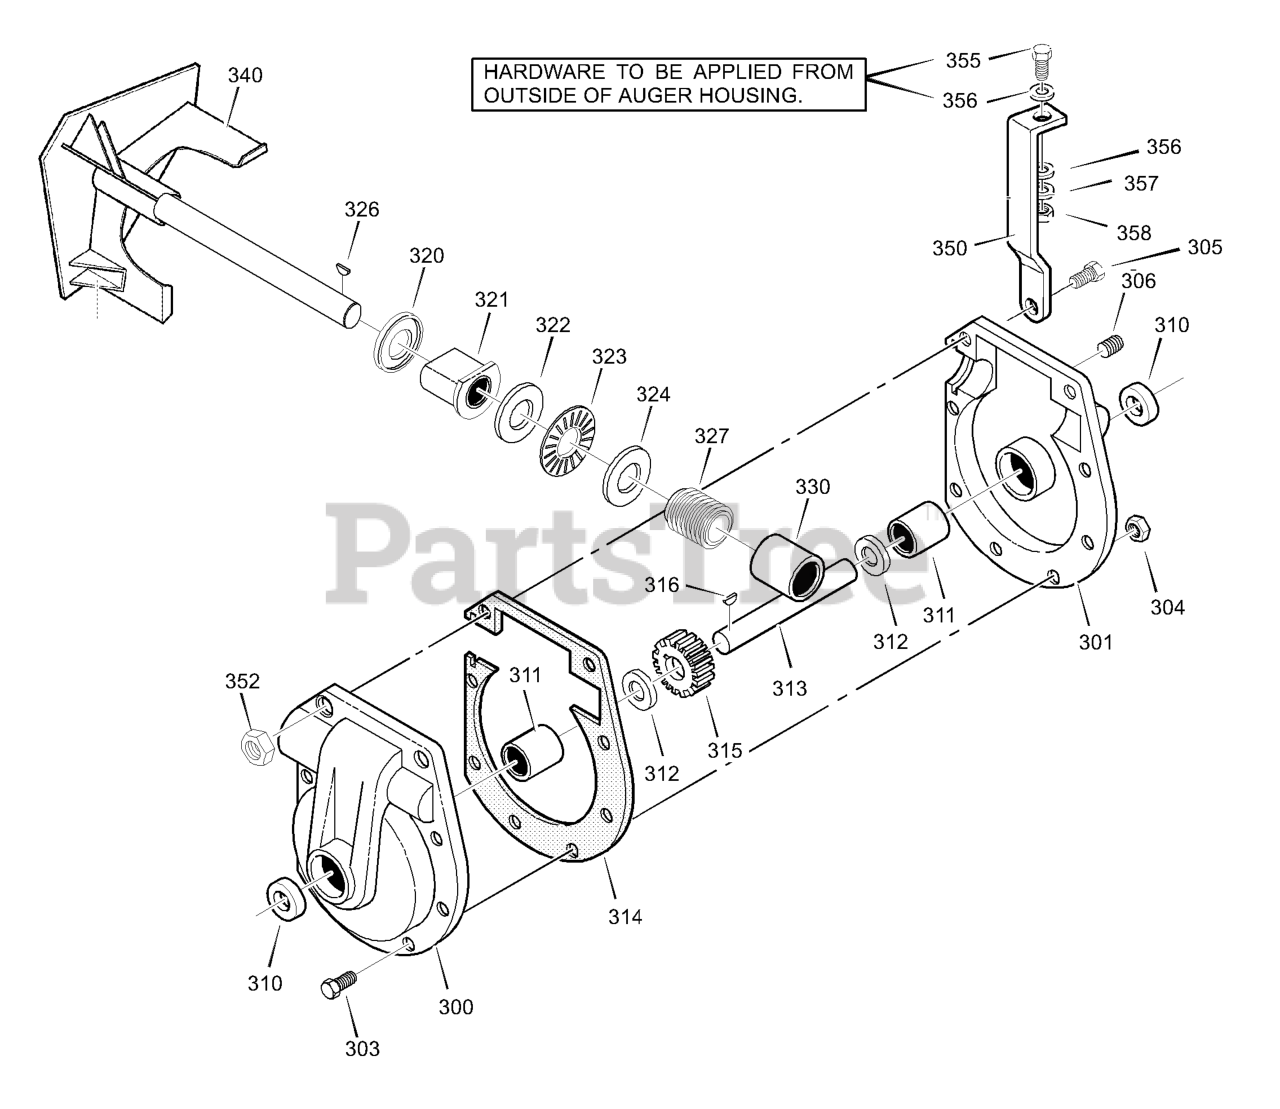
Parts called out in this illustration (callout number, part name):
300	CASE, GEAR, RH
301	CASE, GEAR, LH
303	SCREW,5/16-24 x 1.00
304	NUT, 5/16-24
305	SCREW, 5/16-18 x 1.50
306	PLUG, PIPE 1/4-18
310	SEAL, OIL
311	BEARING, SLEEVE
312	WASHER, FLAT
313	SHAFT, AUGER OUTPUT
314	GASKET, GEAR BOX
315	GEAR, WORM
316	KEY, WOODRUFF #61
320	RING, QUAD
321	BEARING, FLANGED
323	BEARING, ROLLER
324	WASHER, FLAT
350	LF BRACE, GEAR BOX
352	NUT, 5/16-24
355	SCREW 5/16-18X1.25
356	WASHER
357	WASHER
358	NUT 5/16-18
